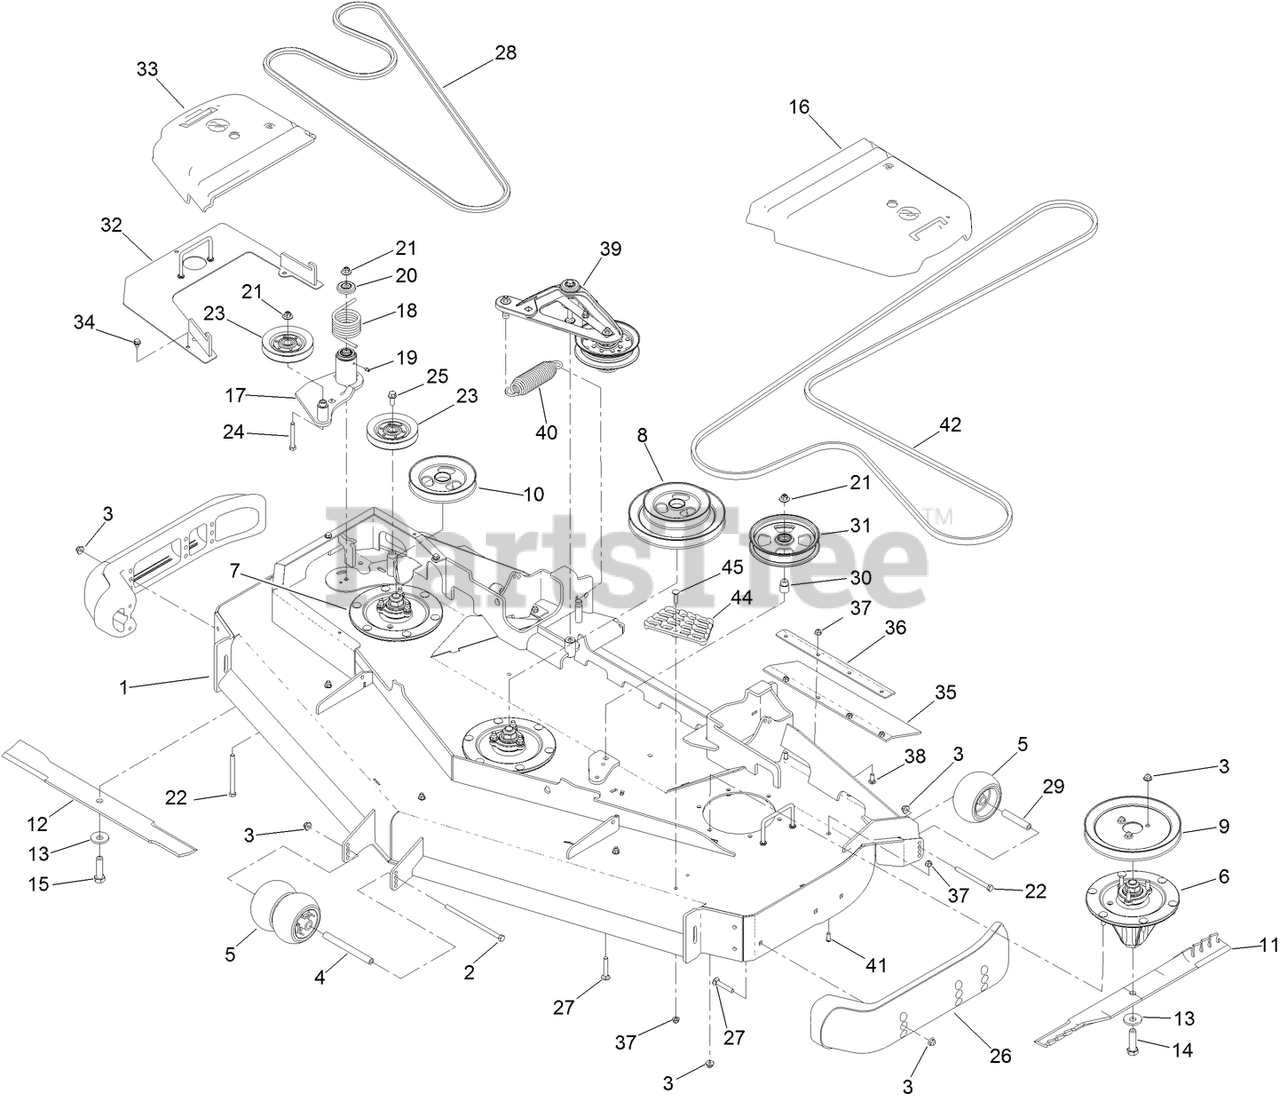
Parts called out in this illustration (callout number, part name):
1	DECK DECAL ASM
2	SCREW-HH
3	NUT-HF, NI
4	SPACER-WHEEL
5	ROLLER-SCALP, ANTI
6	SPINDLE ASM
7	LH SPINDLE ASM
8	PULLEY ASM
9	SHEAVE
10	PULLEY
11	BLADE-ATOMIC, 24.5IN
12	BLADE-ROTARY, 24.5IN (LOW FLOW)
13	WASHER-BLADE BOLT, HEAVY
14	SCREW-BLADE
15	SCREW-BLADE, LH
16	COVER-BELT, LH
17	IDLER ASM
18	SPRING-TORSION
19	FITTING-GREASE
20	GUARD-TOP
21	NUT-FLANGE, NI
22	SCREW-HH
23	SHEAVE
24	SCREW-HH
25	SCREW-HHF
26	SKID-BUMPER, DECK
27	SCREW-HH
29	TUBE-SPANNER
30	BUSHING-IDLER
31	PULLEY-IDLER, FLAT
32	COVER-REVERSE DRIVE
33	COVER-BELT, RH
34	SCREW
35	GUARD-TIRE
36	SUPPORT-OUTER FLAP
37	NUT-HF, NI
38	SCREW-CARR
39	DECK IDLER ASM
40	SPRING-EXTENSION
41	SCREW-HSBH
44	STEP-DECK
45	SCREW-CARR
